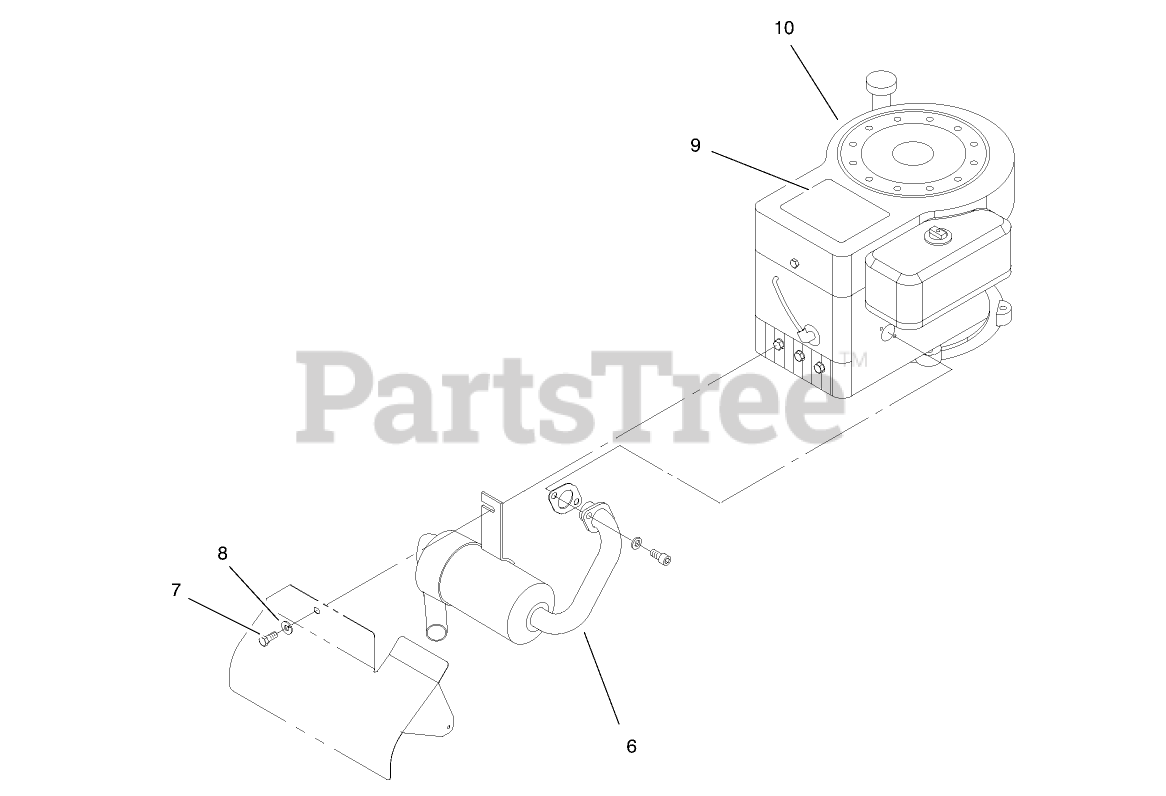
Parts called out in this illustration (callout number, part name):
6	MUFFLER
7	SCREW-HH
8	WASHER-LOCK
10	Engine-13 Hp BS Carb)
